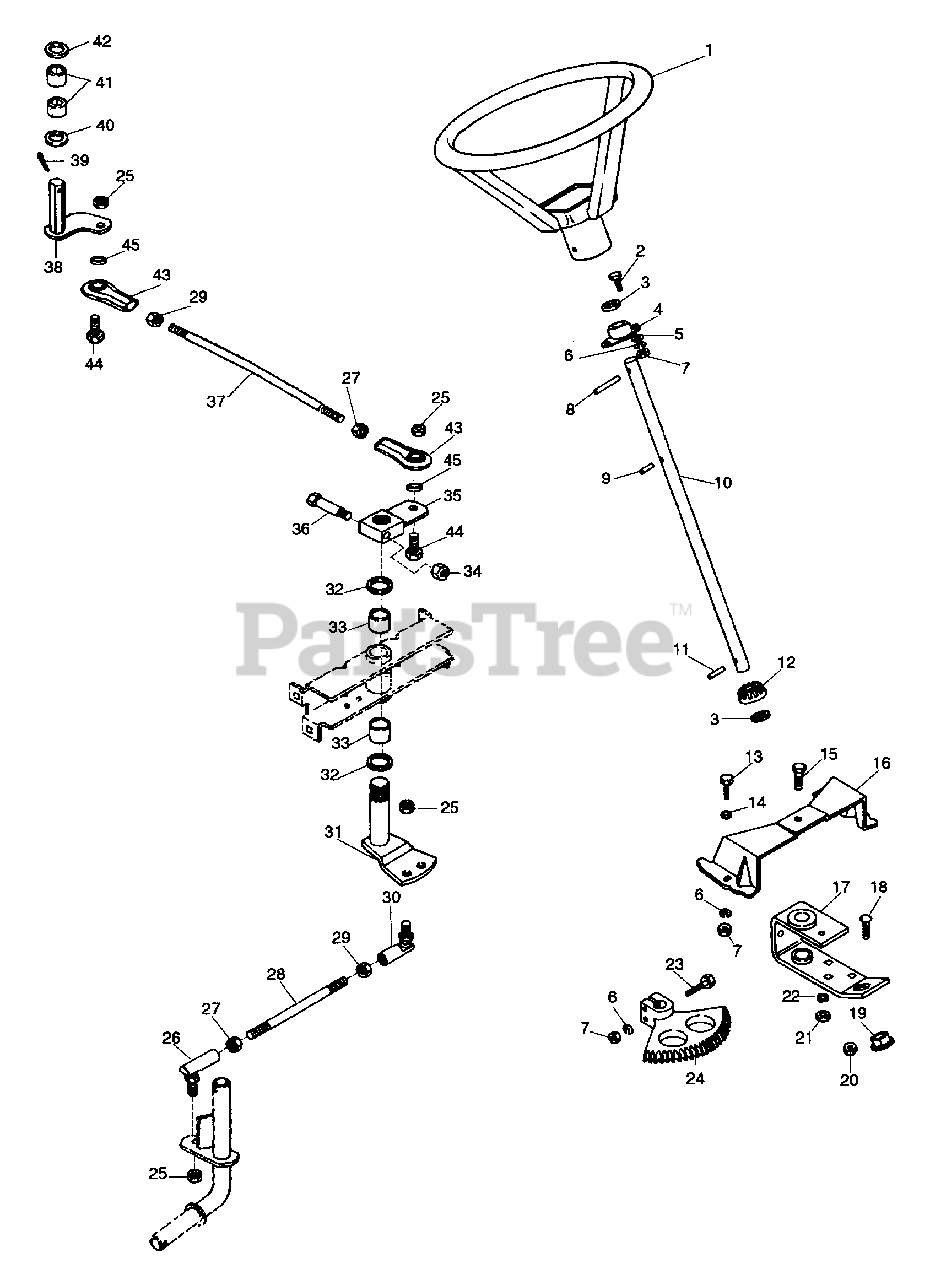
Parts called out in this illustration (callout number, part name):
1	LOGO-STEERING WHEEL
1	STEERING WHEEL ASSEMBLY
1	CLIP-U FASTNG KELCH
1	STEERING WHEEL CAP
2	BLT-HEX .31-18X.75 PL GR2
3	WSHR-FL-STL .754X1.125X.062 PL
4	BRG-FLG .751X2 HOLESX.81
5	WSHR-FL-STL.312X.734X.065PL
6	WSHR-LK .312X.097 PL HVY
7	NUT-HEX .312-18
8	PIN-ROLL .250X2.00
9	PIN-ROLL .188X1.00
10	STEERING COLUMN
11	PIN .249X1.125 DRIV-LOK SP
12	PINION GEAR-STEERING
13	BLT-HEX .31-18X1.00 PL GR 2
14	WSHR-FL-STL .323X.625X.062 PL
15	BLT-HEX .38-16X1.00 PL
16	STEERING SUPPORT BRACE
17	STEERING BRACKET
18	BLT-RDHDSQNK .38-16X1.0 PL
19	BSHG-FLG .750X1.093X.625X1.375
20	NUT-LK-FLG .375-16 PL
21	NUT-HEX .375-16
22	WSHR-LK .375X.115 HVY PL
23	BLT-HEX .31-18X1.75 PL GR2
24	STEERING BEVEL GEAR
25	NUT-LK .50-20 PL
26	BALL JOINT L.H.
27	NUT-JAM .50-20 LH THD PL
28	TIE ROD
29	NUT-JAM .50-20 PL
30	BALL JOINT R.H.
31	STEERING PIVOT
32	PLASTIC WASHER
33	BSHG-SLV 1.000X1.125X.875
34	NUT-LK-CROWN .50-13 GR C PL
36	LOCK BOLT
37	STEERING LINK
38	ARM & SHAFT
39	PIN-COTR .18X1.25 PL
40	WSHR-FL-STL .880X1.250X.062
41	BSHG-SLV .750X1.000X.750 HX SB
42	WSHR-FL-STL .875X1.250X.075
43	ROD END, 1/2 RH
44	BLT-HEX .50-20X1.75 PL GR5
45	BSHG, SPCR.500X.750X.321 PM
